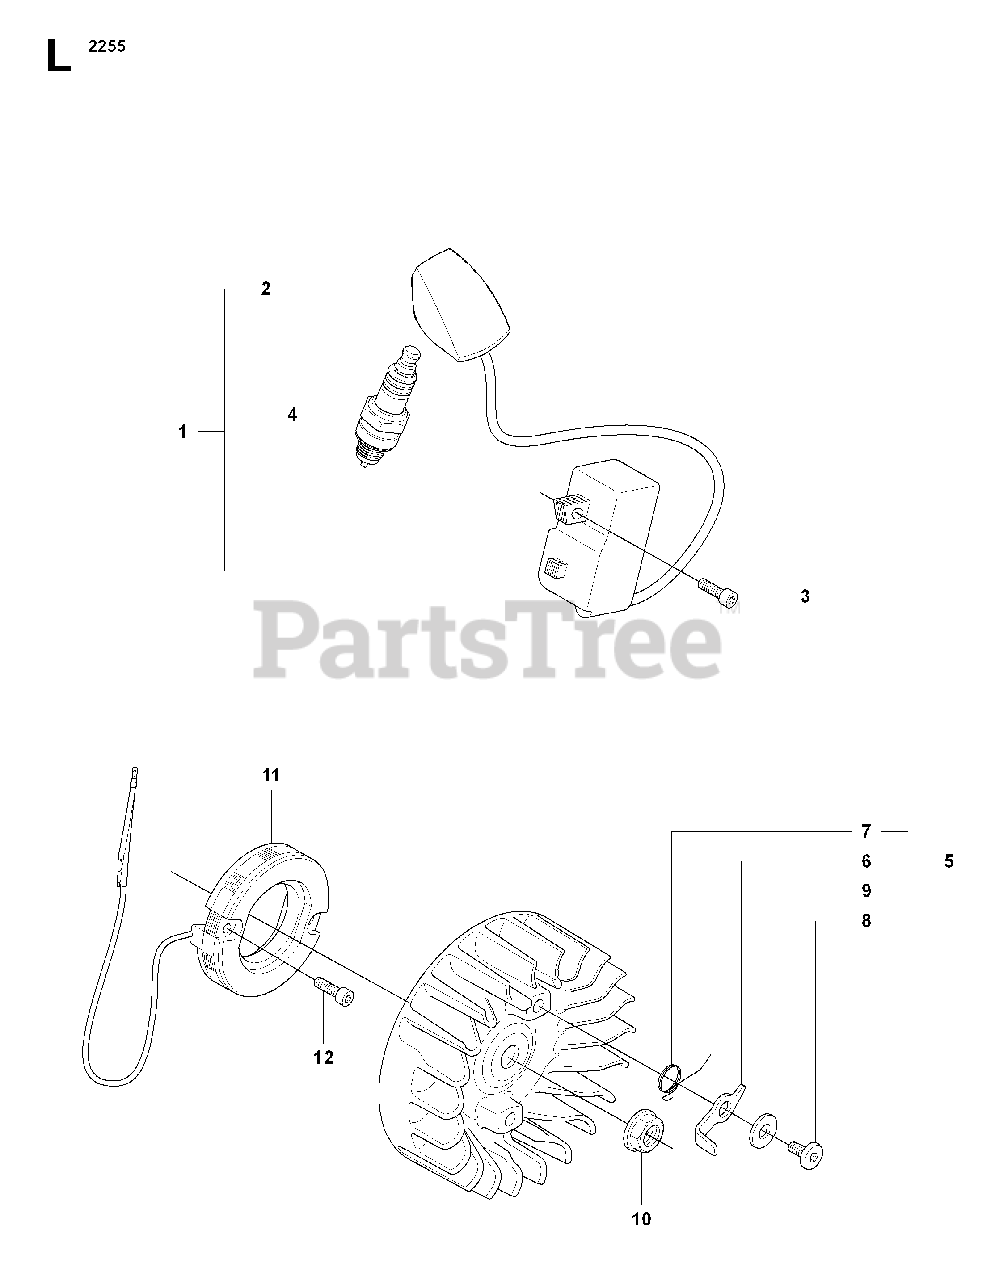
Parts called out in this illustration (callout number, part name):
4	BPMR7A NGK SPARK PLUG
5	FLYWHEEL ASSY
6	STARTER PAWL
7	SPRING
8	PIN, STARTER CATCH
9	WASHER
10	NUT W/ WASHER
11	GENERATOR STARTER
12	SCREW
